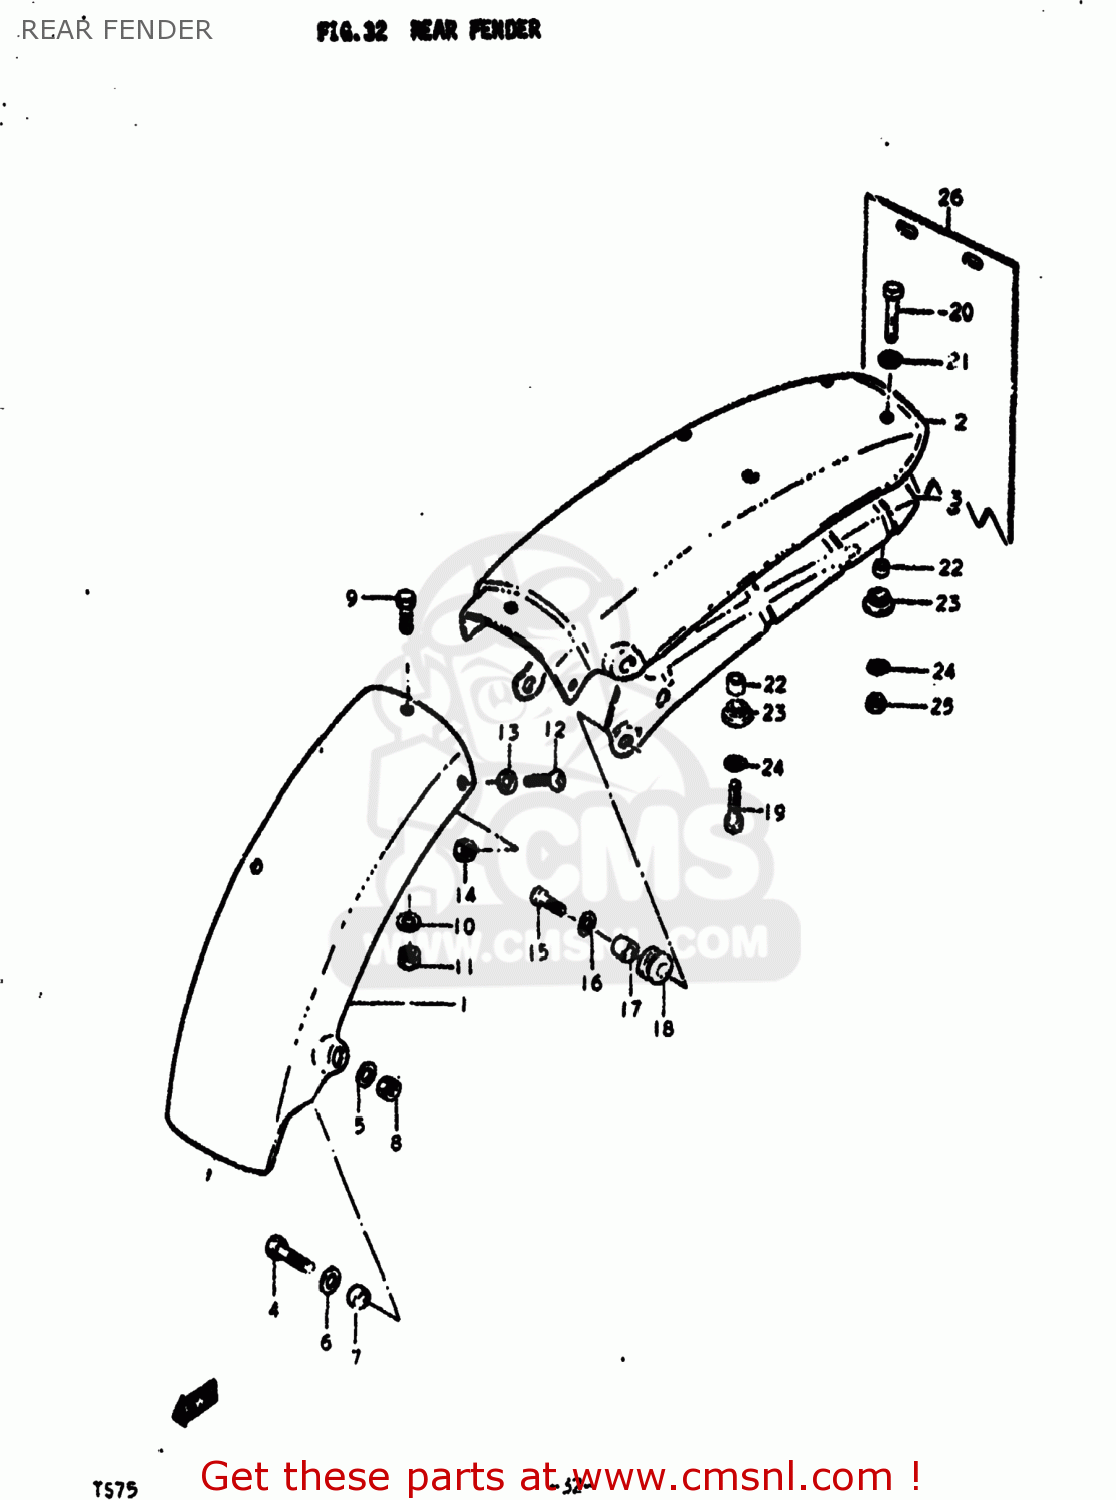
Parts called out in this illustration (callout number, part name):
1	FENDER,REAR
2	FENDER,REAR
3	REINFORCEMENT,REAR FENDER
4	BOLT
5	WASHER 6MM
6	WASHER (6.5X20X1.2)
7	SPACER
8	NUT
9	BOLT
10	WASHER(6.5X16X1.2)
11	NUT
12	SCREW
13	WASHER 5MM
14	NUT
15	BOLT
16	LOCK WASHER
17	SPACER(6.1X9X7.5)
18	CUSHION
19	BOLT(6X18)
20	BOLT
21	WASHER 6MM
22	SPACER
23	CUSHION
24	LOCK WASHER
25	NUT
26	MUD GUARD,REAR FENDER
